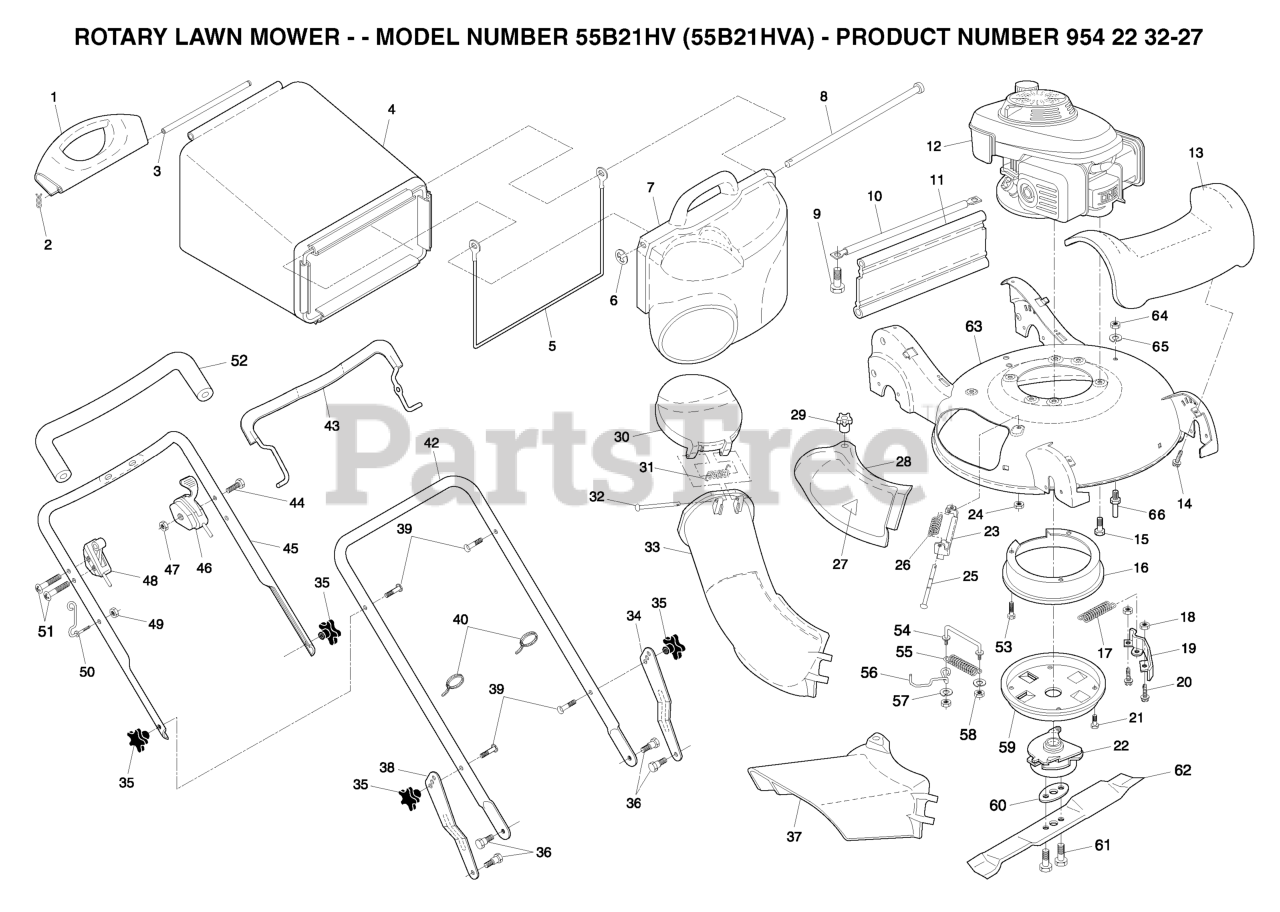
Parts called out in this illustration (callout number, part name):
2	COTTER PIN (3 2)(2 2MC)
3	ROD.REAR.HANDLE.YELLOW
4	GRASSBAG
8	ROD, PIVOT
9	SCREW.HWH.13-16X1.12
14	SCREW
15	BOLT 3/8-16X1-1/8
16	BLADE.21".BBC
17	SPRING.BBC
18	NUT T
20	BOLT
21	TAPPING SCREW
23	BRACKET.ASM.HINGE
24	LOCK NUT
25	ROD.HINGE.1/4"3.82"
26	SPRING.MULCH.DOOR
27	DECAL HYT
29	KNOB.MULCH.DOOR
32	ROD.HINGE.1/4"3.82"
34	BRACKET
35	KNOB.HANDLE.STAR.HUSQ.GRAY
36	SHOULDER BOLT
37	GUARD.CLIP.ON.21.HV.GRAY
38	BRACKET ADJ LOWER HNDLE RH
39	HANDLE BOLT
40	TIE GUIDE
42	HANDLE.LOWER.GREY
43	BAIL
45	HANDLE.ASM.UPPER.W/GRIP
46	BLADE BRAKE CONTROL
48	THROTTLE
50	ROPE GUIDE
52	GRIP.HANDLE.FOAM.WIDE.(1 SIDE)
54	LINK.TORQUE.BBC
55	SPRING.LINK.BBC
62	BLADE.21".BBC
64	NUT LOCK FLG 3/8-16 UNC
65	LOCKWASHER
66	STUC.GUIDE.BELT.RWGD
